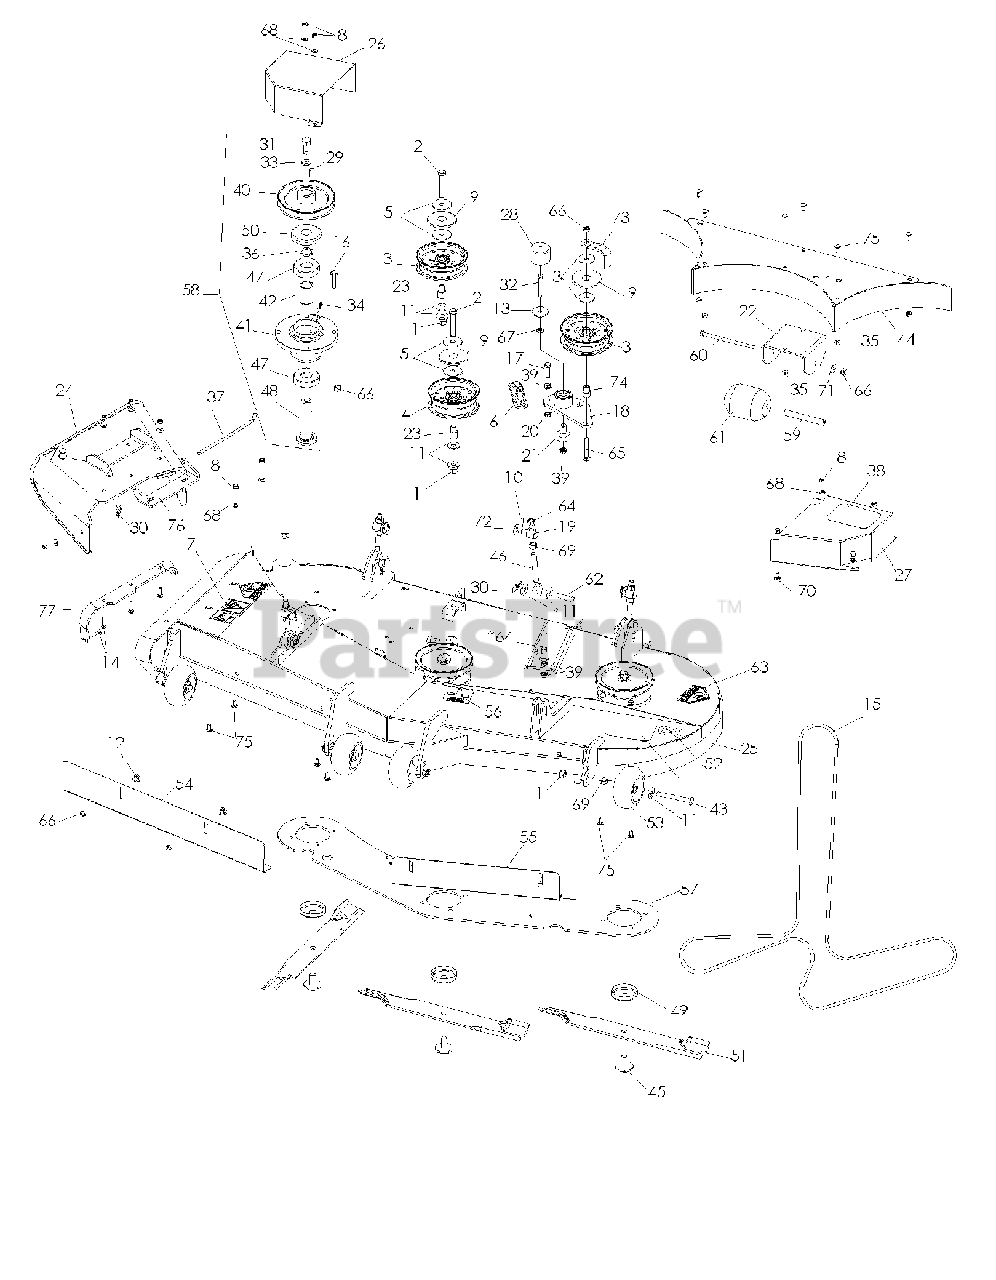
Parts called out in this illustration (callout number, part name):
1	NUT 1/2-13 HEX NYLOC ZD
2	SCREW, 1/2C X 3 HEX CAP
3	IDLER PULLEY
4	IDLER PULLEY (TALL)
5	ISOLATOR WASHER
6	DECK SPRING
7	DECAL, EURO SEVERING
8	NUT 5/16 NYLOC
9	TOP DUST CAP
10	PIN COTTER 1/8 X 1 ZD
11	WASH USS FLAT 1/2
12	RHSNB 3/8-16 X 3/4 GR5 ZD
13	WASHER, 3/8 SPEC
14	RHSNB 5/16-18 X 1-1/2 GR 5 ZD
15	BELT, DECK 52 COMBI/60 GRIZZY
16	HCS 3/8C X 1 1/2
17	HCS 3/8-16 X 1-1/2
18	ARM-IDLER W/BRG
20	NUT 3/8-16 HEX JAM
21	PIVOT, BEARING
22	REAR CENTER ROLLER BKT 60 BLK
23	SPACER - IDLER
24	CHUTE, RUBBER DISCHARGE 60"
25	DECK W/DECAL 60" GRIZZLY
26	PULLEY GUARD RH 60 PAINTED
27	PULLEY GUARD LH 60 PAINTED
28	CAP, VINYL
29	KEY - 1/4 X .88
30	PIN, COTTER 1 3/4
31	1/2-20 UNF X 1 1/4 HHBLT
32	HCS 3/8C X 2 1/2
33	WASHER .525 X 1.375 X .25
34	ZERK, 3/16, DRIVE IN
35	5/16-18 FLANGED L-NUT
36	SPACER .25
37	DEFLECTOR PIN
38	REAR FLOOR PAD-LH
39	NUT 3/8C WHIZ
40	PULLEY 6.45 METRIC
41	DECK HUB MACHINED
43	HCS 1/2-13 X 4 GR 5 ZD
44	W-BAFFLE WLDT.
45	BLADE BOLT/WASHER
46	BOLT, EYE
47	BEARING - 6305 - 2RS
48	SHAFT SHORT
49	TRASH GUARD
50	TRASH GUARD
51	BLD 60" HI LIFT FUSION
52	DECAL, 60"
53	GAUGE WHEEL
54	BLOW BY BAFFLE
55	BLOW BY BAFFLE LH 60
56	DECAL, BELT ROUTING (18656)
57	HUB STIFFENER PLATE
58	SPINDLE ASSEMBLY
59	BUSHING
60	3/8-16 X 6-1/2 HHB GR8
61	ROLLER 3-3/4 DIA. X 4-1
62	CLEVIS PIN 1/2X1-3/4LG
63	DECAL, CPSC
64	HCS 3/8C X 1
65	RHSNB 3/8-16 X 2.75
66	NUT 3/8-16 NYLOC
67	WASHER 3/8 SAE FLAT
68	FLAT WASHER 5/16 SAE
69	NUT HEX 1/2
70	BOLT 5/16C X 3/4" CARRIAGE
71	WASHER 3/8 FLAT
72	WASHER 1/2 FLAT
73	GUIDE, BELT
74	BUSHING, IDLER
75	RHSSNB 5/16C X 1.0
76	PIVOT BRACKET - DECK
77	BRKT REINF-CHUTE 60"
78	PIVOT BRKT RUBBER CHUTE
